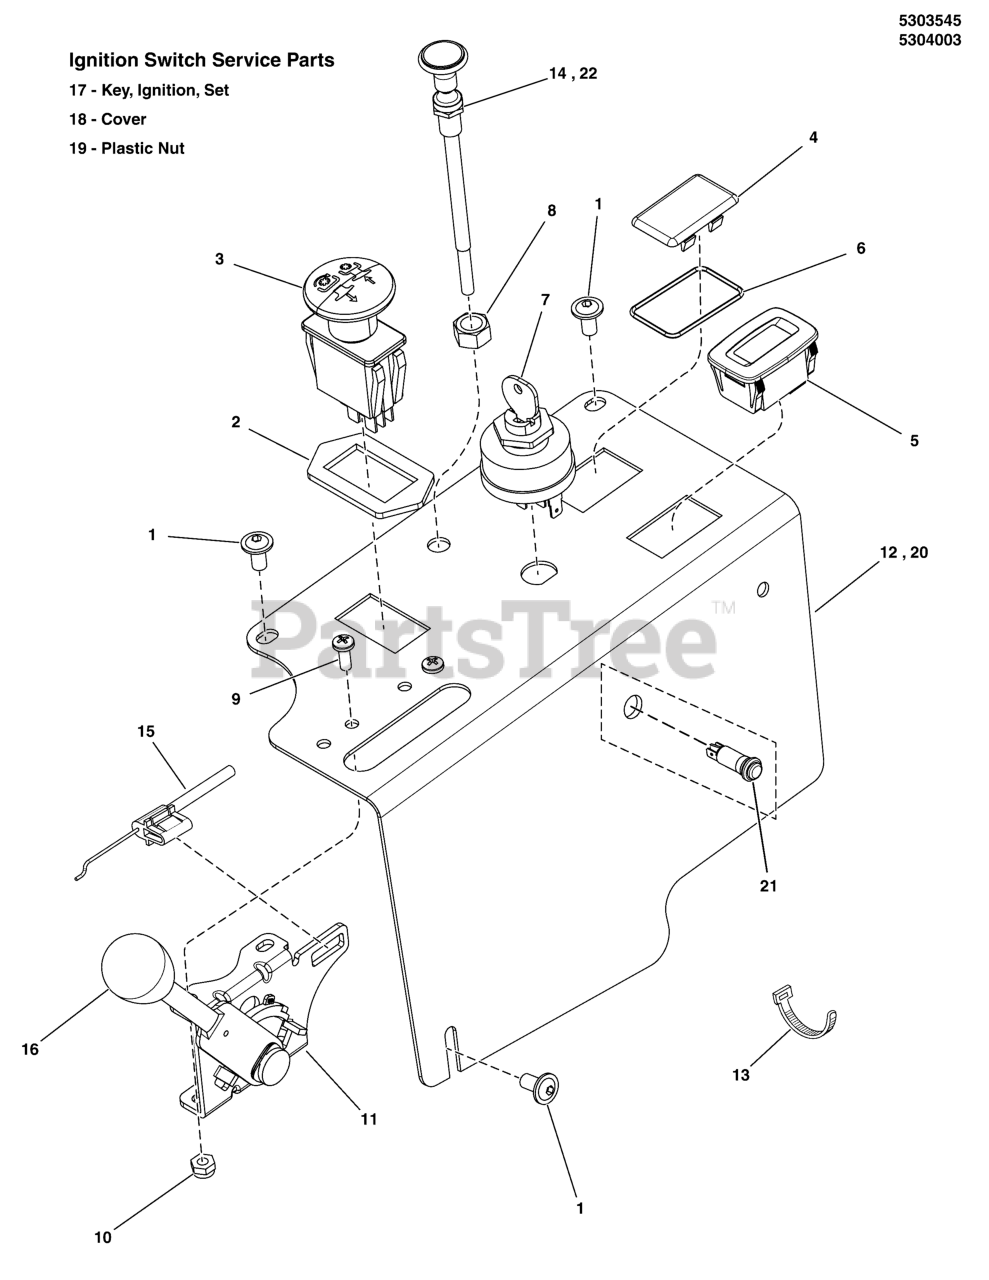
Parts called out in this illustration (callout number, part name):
1	SCREW, ALLEN HEAD 1/4-20X.500 ZINC PHOS
2	RING, SWITCH RETAINER
3	SWITCH-PTO PUSH
4	PLUG, .820X1.44 HOLE, BLACK PLASTIC
5	HOUR METER
6	O-RING, 7/8" ID X 1/16" W
7	SWITCH, IGNITION, 6 POST
8	NUT, 3/8-24 HEX (SV)
9	SCREW, #10-24 X 3/4" ROUND PHILLIPS
10	NUT, Hex, Nylon Lock, #10-24
11	LEVER, THROTTLE CONTROL, HEAVY-DUTY
12	PLATE, CONTROL PANEL, S150XT - BLK
13	TIE, SELF-LOCKING, 6"
14	CABLE, CHOKE CONTROL, 43.5"
15	CABLE, THROTTLE, 42"
16	THROTTLE CONTROL HANDLE/KNOB
17	KEY, IGNITION MOLDED SET
18	COVER, PLASTIC, SNAP ON
19	PLASTIC NUT
20	PLATE, CONTROL PANEL, S150XT, EFI -BLK
21	LIGHT, INDICATOR, PANEL, LED, RED
22	CABLE, Choke Control, 47"
